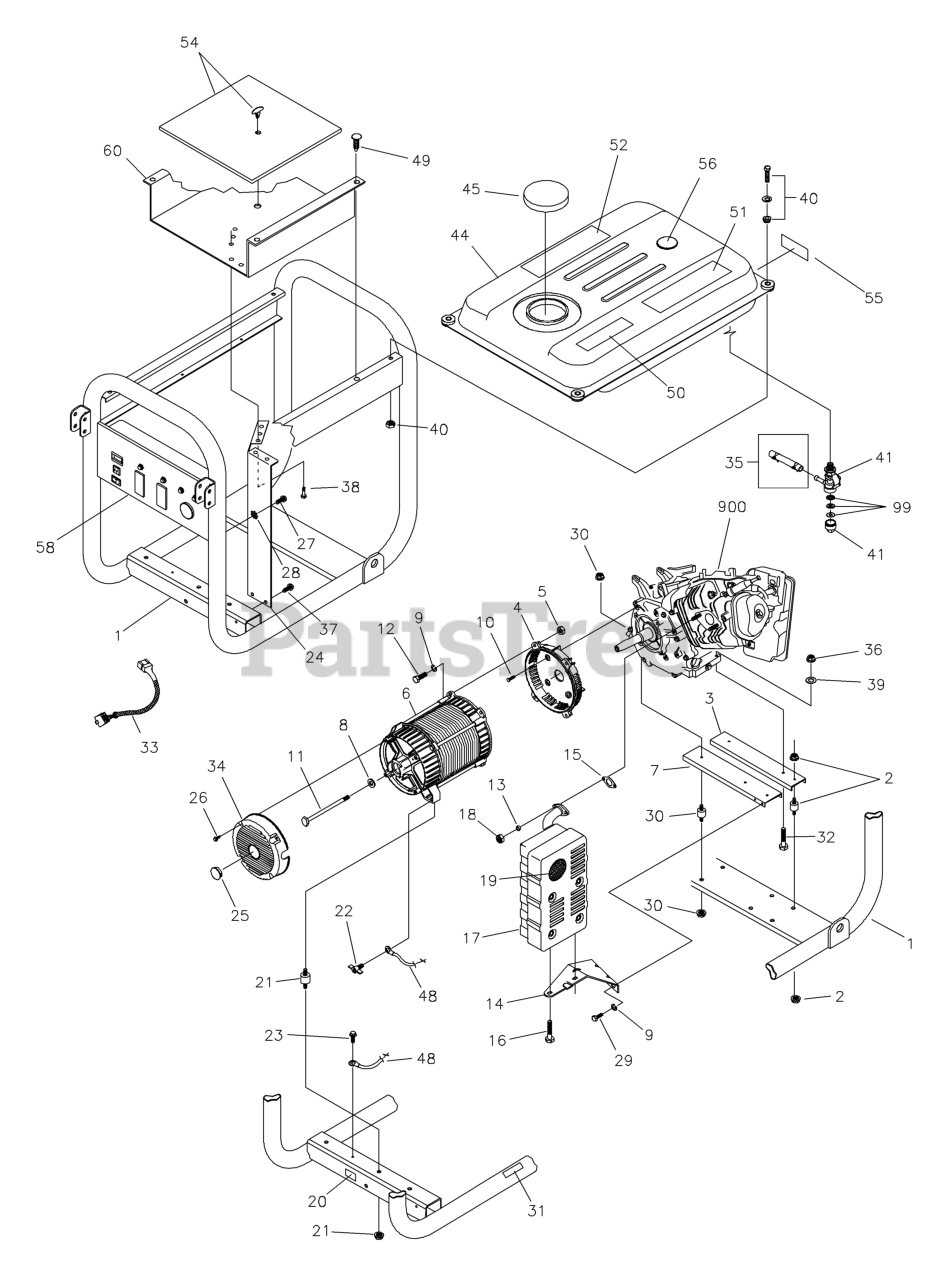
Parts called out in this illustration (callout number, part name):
1	KIT, Cradle
2	KIT,Vibration Mount
3	SUPPORT, Engine
4	HOUSING, Engine Adapter
6	ASSY,Alternator
7	SUPPORT, Eng/Muffler
8	WASHER, M8 Flat
9	WASHER, 5/16-M8, Lock
10	SBHCS, 3/8-16 x 1.0 Lg.
11	HHCS, 5/16-24 x 7.75
13	SPACER, 3/8 x 3/4 x 3/8
14	BRACKET, Muffler
15	GASKET, Muffler
18	NUT, Flange Serrated
19	SCREEN, Spark Arrest
20	DECAL, Ground
21	KIT,Vibration Mount
22	SCREW,Wing, M6 - 1.0 x 16
23	SCREW, 10 - 16 x 3/4, Self Drill
24	SHIELD, Heat
26	TAPTITE, M5-0.8 x 10
27	SCREW, 12-14 x 7/8, Self Drill
30	KIT,Vibration Mount
31	DECAL, Hot Muffler
33	HARNESS,Wire, Power
34	COVER, Bearing Carrier w/ Cap
35	KIT, Fuel Line (cut to fit)
36	NUT, 5/16-18, Flange Serrated
37	SCREW, 12-24 x 1/2 Thd Forming
38	SCREW, 10-24 x 1/2 Crimptite
40	KIT, Fuel Tank Hardware
41	VALVE, Fuel
44	ASSY,Tank, Fuel
45	CAP, Fuel
48	WIRE, Ground
49	CLIP,Tree
50	DECAL, Instruction, Fuel Level
51	DECAL, Danger
52	DECAL, Start Instructions
54	KIT, Insulation with Clip
55	DECAL, Fuel Shut-off
56	GUAGE, Fuel
58	ASSY, Control Panel
60	SHIELD, Heat
99	KIT, Fuel Valve Repair
900	ENGINE
